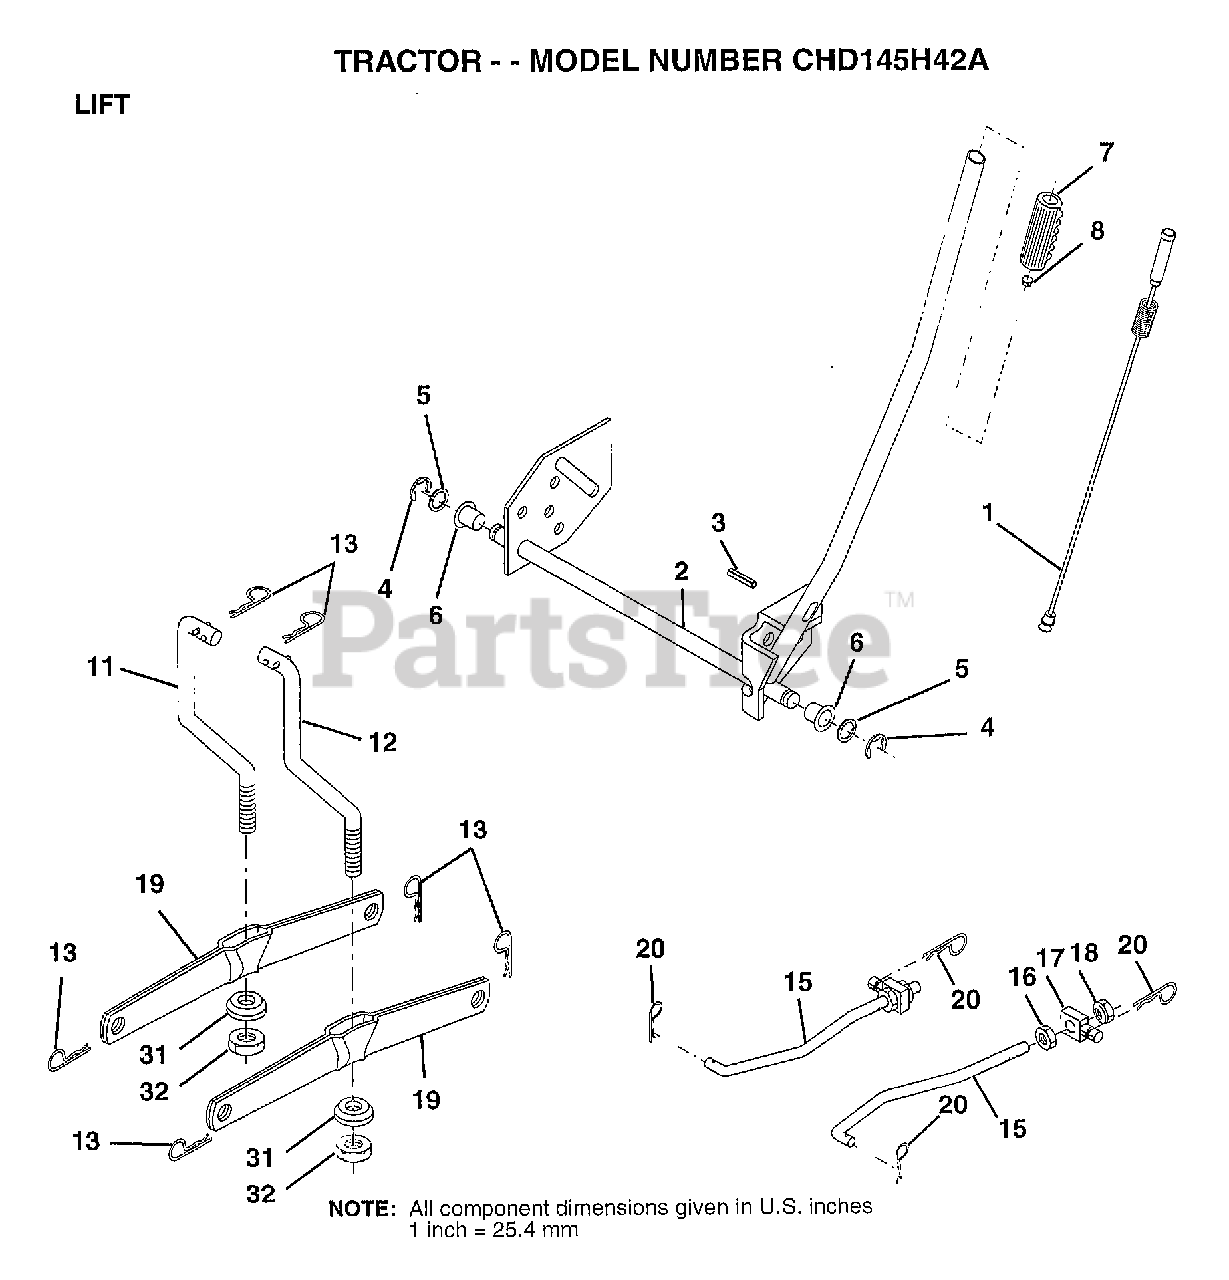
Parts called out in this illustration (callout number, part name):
1	WIRE ASM
2	SHAFT.LIFT.ASM.RH
3	PIN-GROOVE LT
5	WASHER
6	NYLON BEARING
7	GRIP
15	LINK.FRONT
16	NUT
17	TRUNION
18	NUT.LK.W/WSH.1/2.
19	ARM SUSP REAR
20	RETAINER.SPRING
31	BEARING PVT LH
32	NUT.CROWNLOCK.3/8
